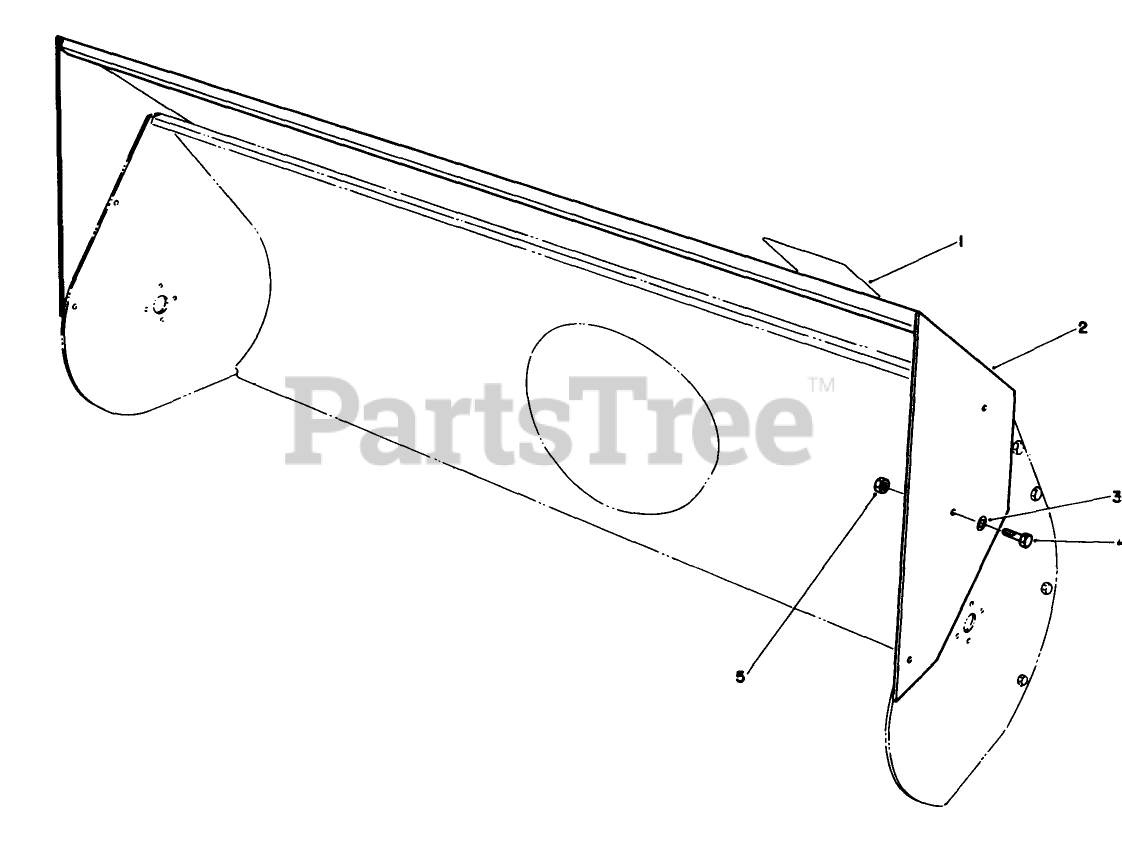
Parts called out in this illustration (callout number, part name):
1	Decal
3	WASHER-FLAT
4	SCREW-HH
5	NUT-LOCK, NI
